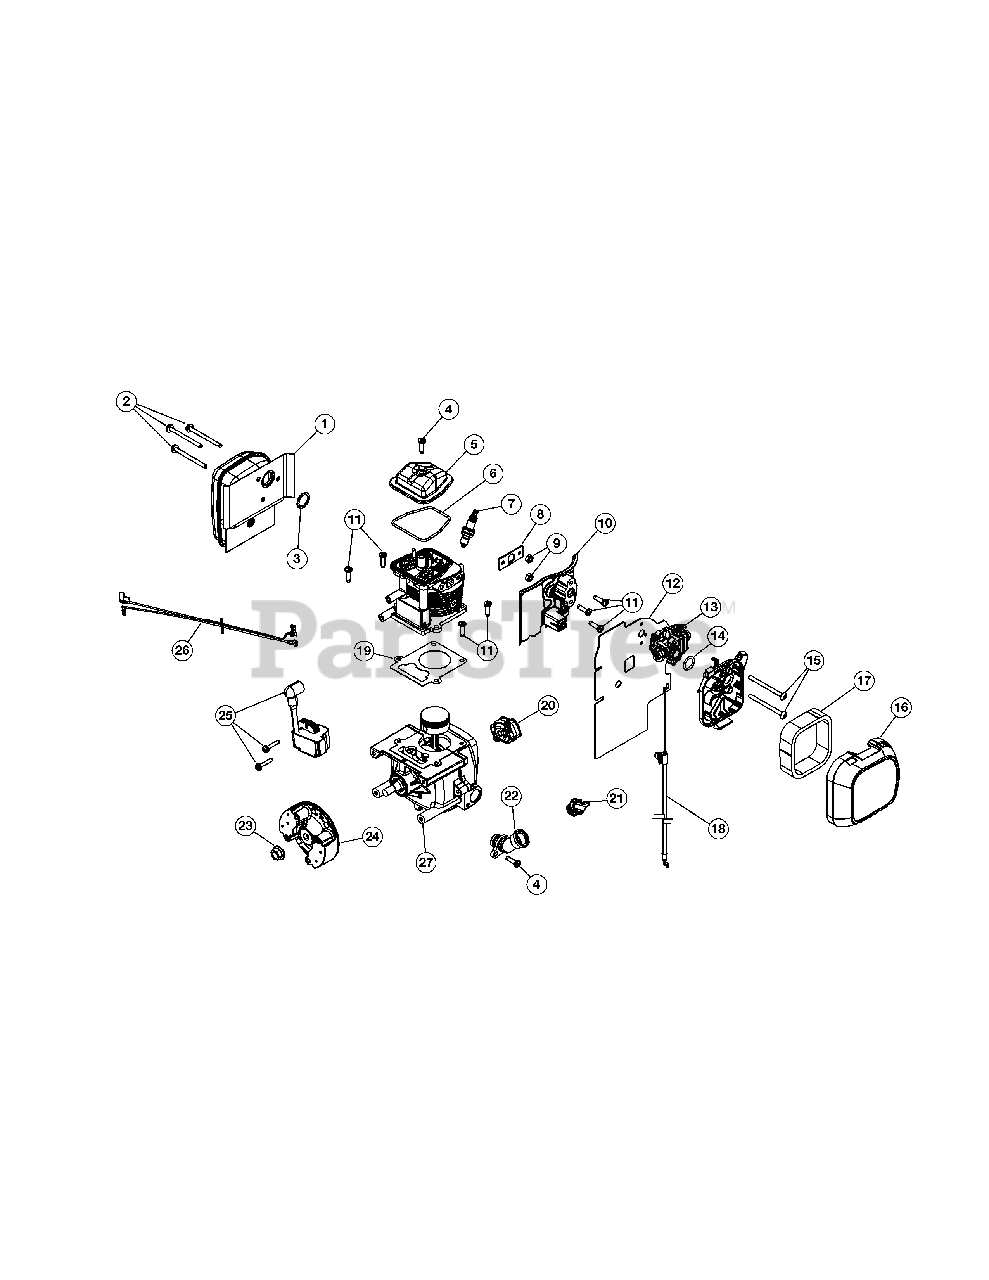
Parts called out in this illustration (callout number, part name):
1	Muffler Assembly (Incl. Ref No. 2 & 3)
2	Muffler Screw
3	Muffler Gasket
5	Rocker Cover
6	Rocker Cover O-Ring
7	Spark Plug
8	Insulator Gasket
10	Insulator
11	Screw
12	Carburetor Gasket
13	Carburetor
14	Carburetor O-Ring
16	Air Cleaner Assembly (Incl. Ref No. 16)
17	Air Filter
18	Throttle Cable
19	Cylinder Gasket
20	Pawl Assembly
21	Oil Plug
22	Oil Fill Tube (Incl. Ref No. 4)
24	Flywheel Asssembly
25	Module Assembly
26	Lead Wire
27	Short Block Assembly
